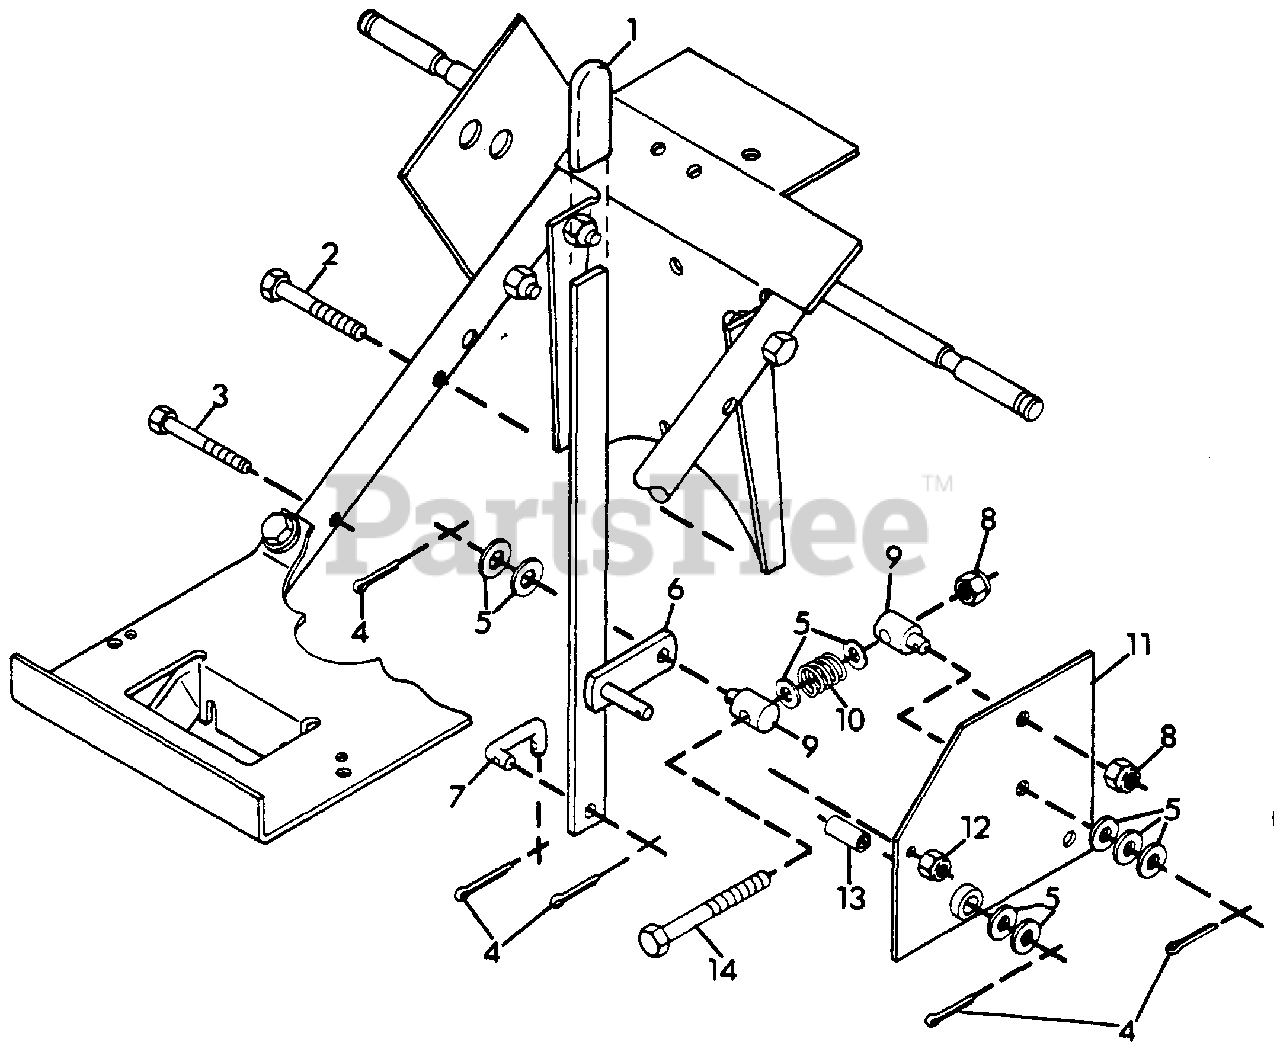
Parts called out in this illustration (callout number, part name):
1	GRIP, HANDLE
2	BOLT, HEX 3/8-16X2.00
3	BOLT, HEX 1/4-20X2.00
4	PIN, COTTER .09X1.00
5	WASHER, FLAT .406X.812X.065
6	LEVER, HI-LO
7	ROD, HI-LO
8	NUT, LOCK 3/8-16
9	PIVOT, BRAKE
10	SPRING, COMP. 1X.78
11	WELDMENT, PLATE HI-LO
12	NUT, LOCK 1/4-20
13	BUSHING, NYLON .375X.503X.875
14	BOLT, HEX 3/8-16X3.25
